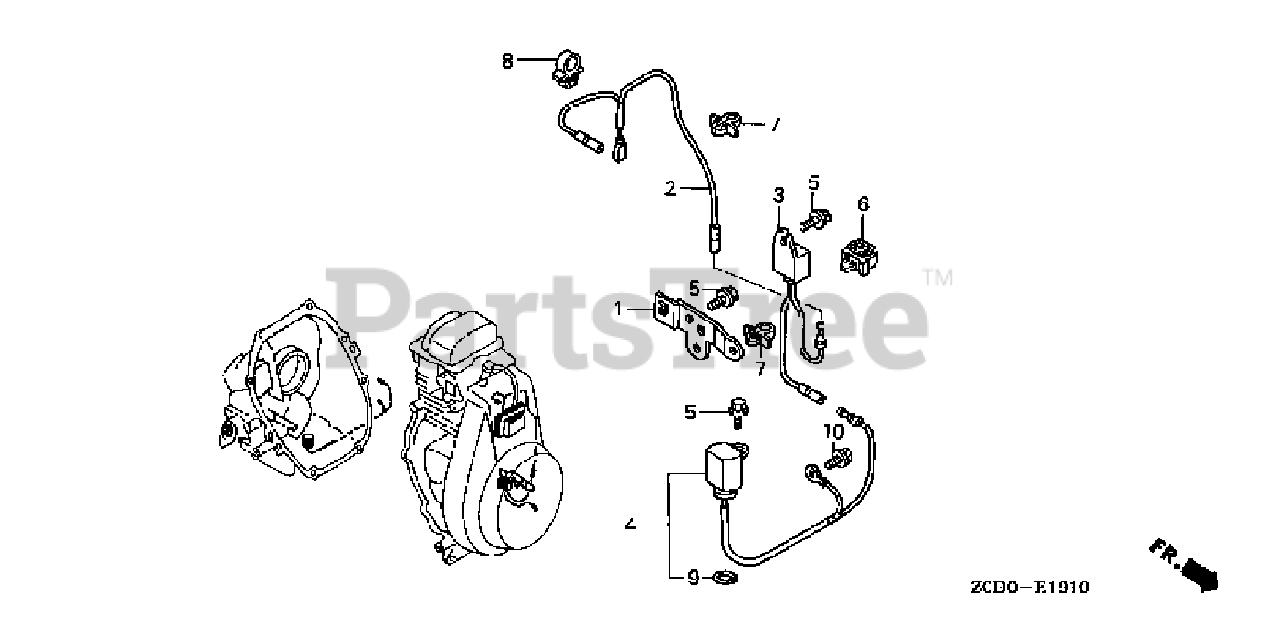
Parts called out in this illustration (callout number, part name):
1	BRACKET, OIL ALERT UNIT
2	WIRE, STOP SWITCH
3	ALERT UNIT, OIL
4	SWITCH ASSY., OIL LEVEL
5	BOLT, FLANGE (6X14)
6	CLIP, WIRE HARNESS (10MM)
7	CLIP, CABLE (A)
8	CLIP B, CABLE
9	O-RING (11.8X2.4)
10	BOLT, FLANGE (6X8)
